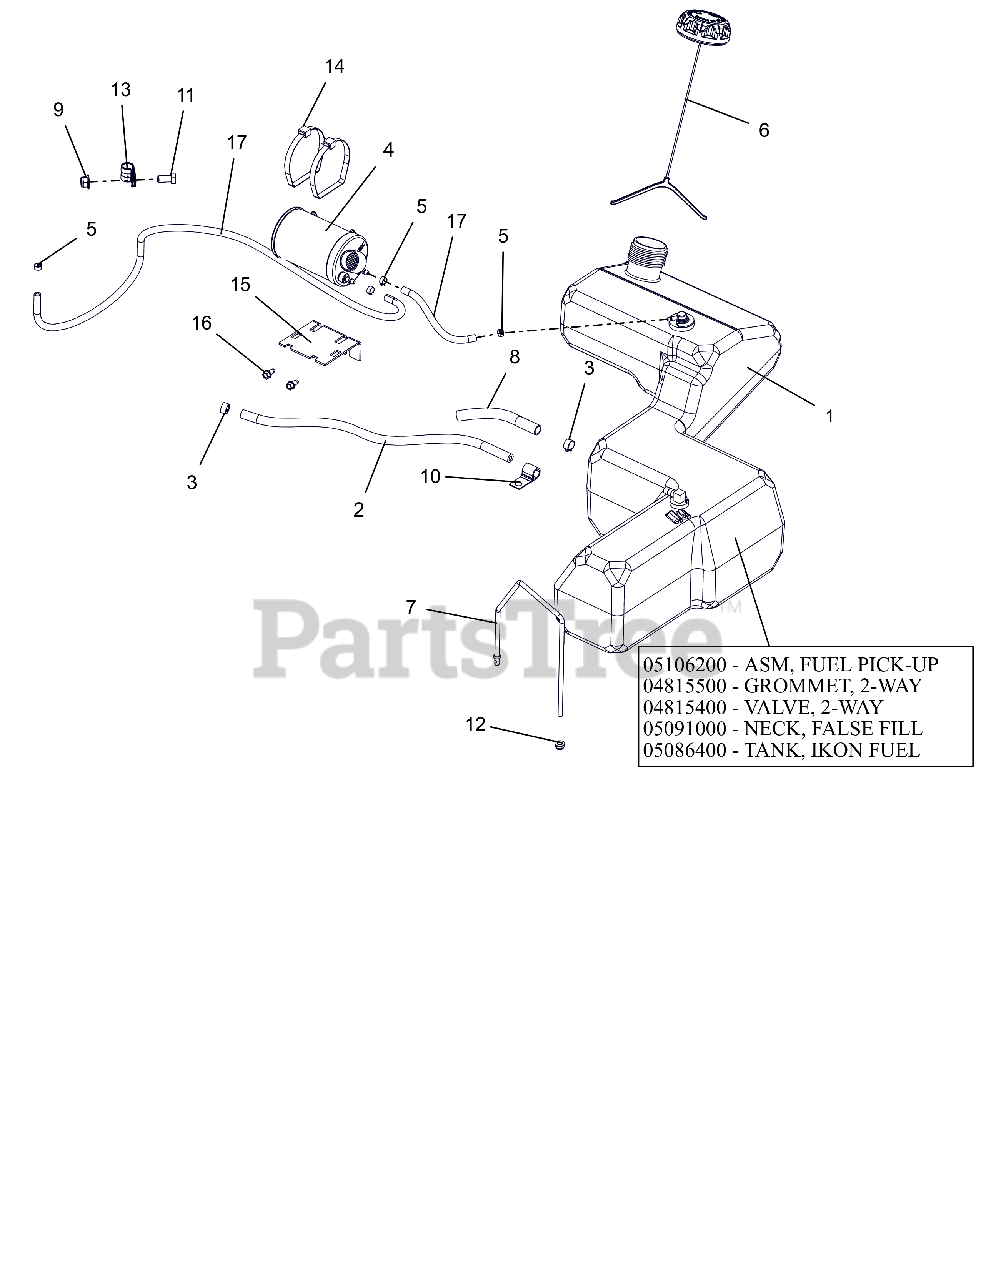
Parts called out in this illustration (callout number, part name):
1	ASSEMBLY, FUEL TANK IKON(2017)
1	ASM, IKON FUEL PICK-UP
1	GROMMET, 2-WAY
1	VALVE, 2-WAY
1	NECK, FALSE FILL-2017 IKON
1	TANK, IKON FUEL (2017)
2	HOSE, .25 LOW-PERM BULK GAS
3	CLAMP, FUEL LINE
4	CARBON CANISTER, 300CC
5	CLAMP-HOSE, SPRING .188
6	CAP, FUEL VENT-IN 2.25" RATCH.
7	BRKT, FUEL TANK HOLD DOWN
8	WRAP, ANTIABRASION .5X.064WALL
9	@NUT-LK-NYL-FLG .38-16 YWZC
10	J-CLAMP
11	@BLT-HEX .38-16X.75 GR5 YWZC
12	@NUT-LK-NYL-FLG .25-20 YWZC
13	CLAMP, CUSHIONED STEEL
14	P-PLASTIC TIE STRAP LARGE
15	BRKT, MOUNT -CARB CANISTER
16	SCR-TAP .25-20X.50 HWH TR YWZ
17	HOSE, .188 30R7 BULK
